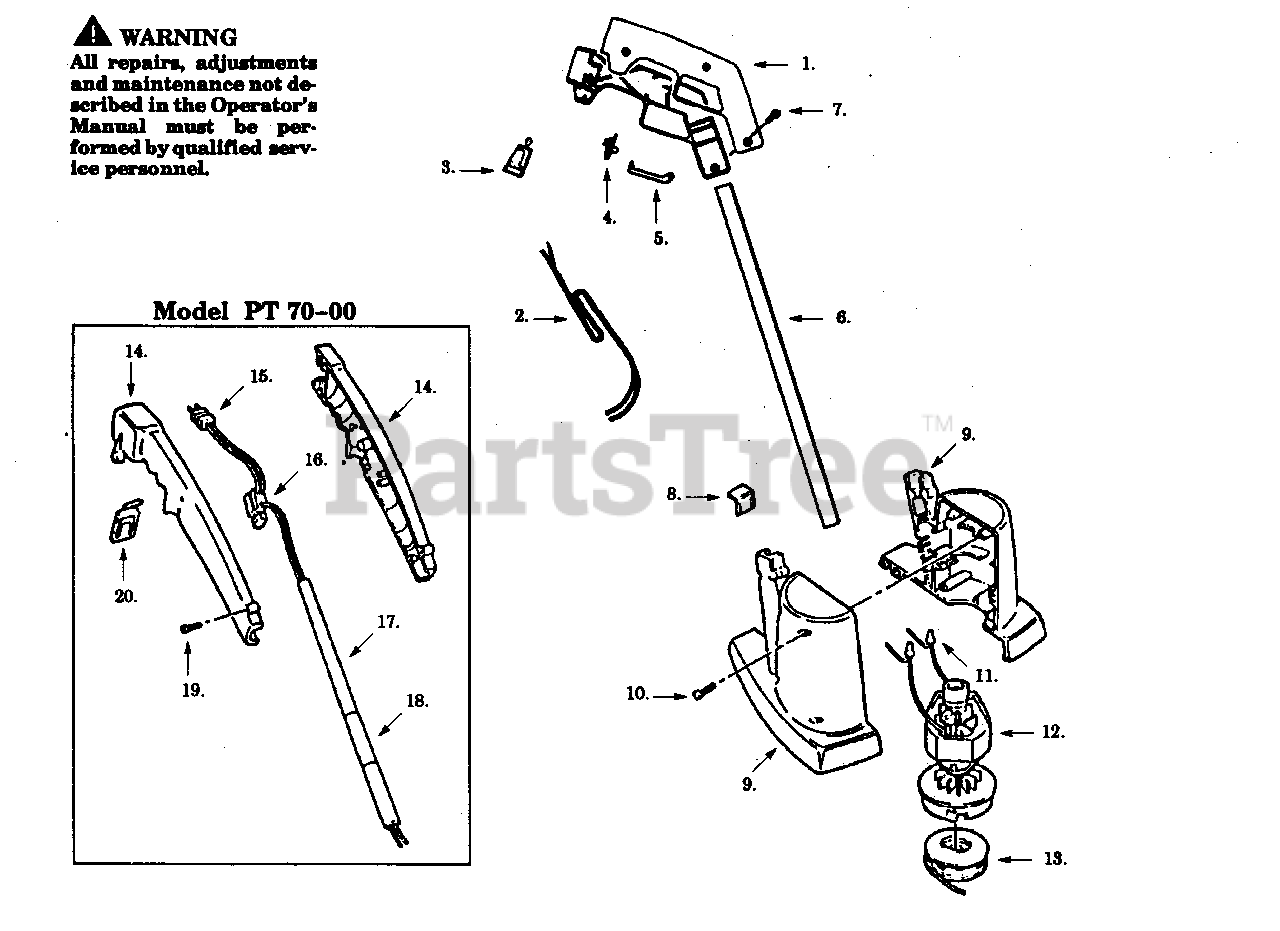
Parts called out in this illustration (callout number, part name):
1	Handle Set
2	Harness Ass'y.
3	Cord Retainer
4	On/Off Switch
6	Tube Assy. w/Decal
8	Line Cutter
9	Housing Set
11	Terminal Cap
12	Motor & Head Ass'y.
13	Spool & Line
14	Handle Set
15	Harness Ass'y.
17	Handle Tube
18	Warning Label
20	Cord Retainer
